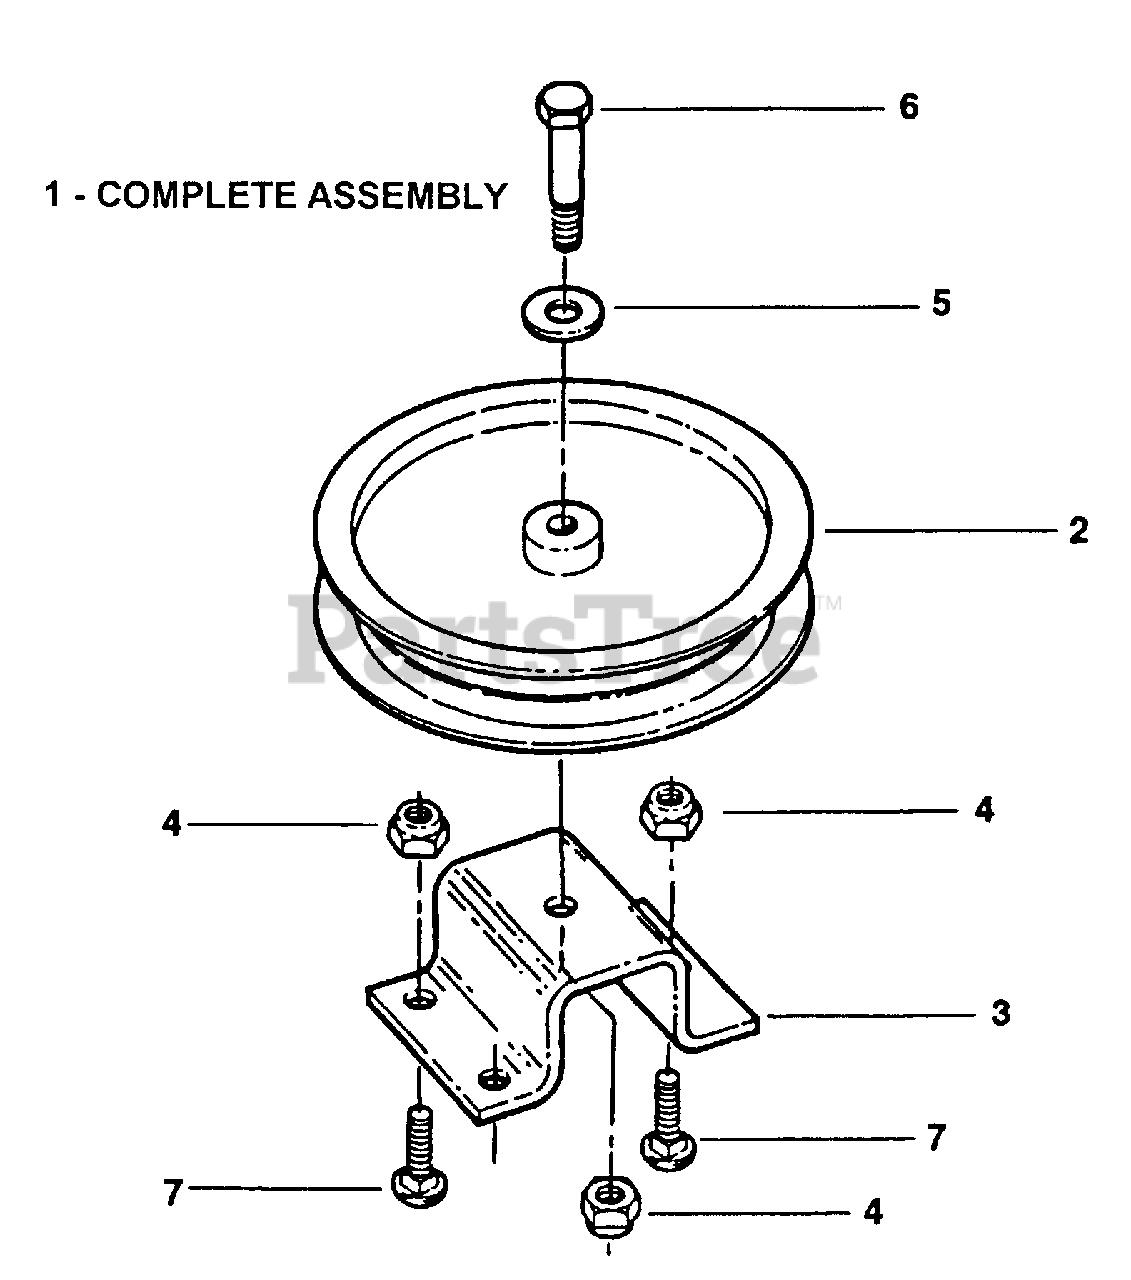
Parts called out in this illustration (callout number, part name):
1	ASSEMBLY, Fixed Idler Group
2	PULLEY, Idler, 5 1/2" O.D.
3	STAND, Fixed Idler
4	NUT, 3/8-16 HEX NYLON LOCK
5	WASHER, 3/8" USS
6	BOLT, 3/8-16 X 2, GD5, CZ
7	BOLT, 3/8-616 x 1" Round Head Square Neck
